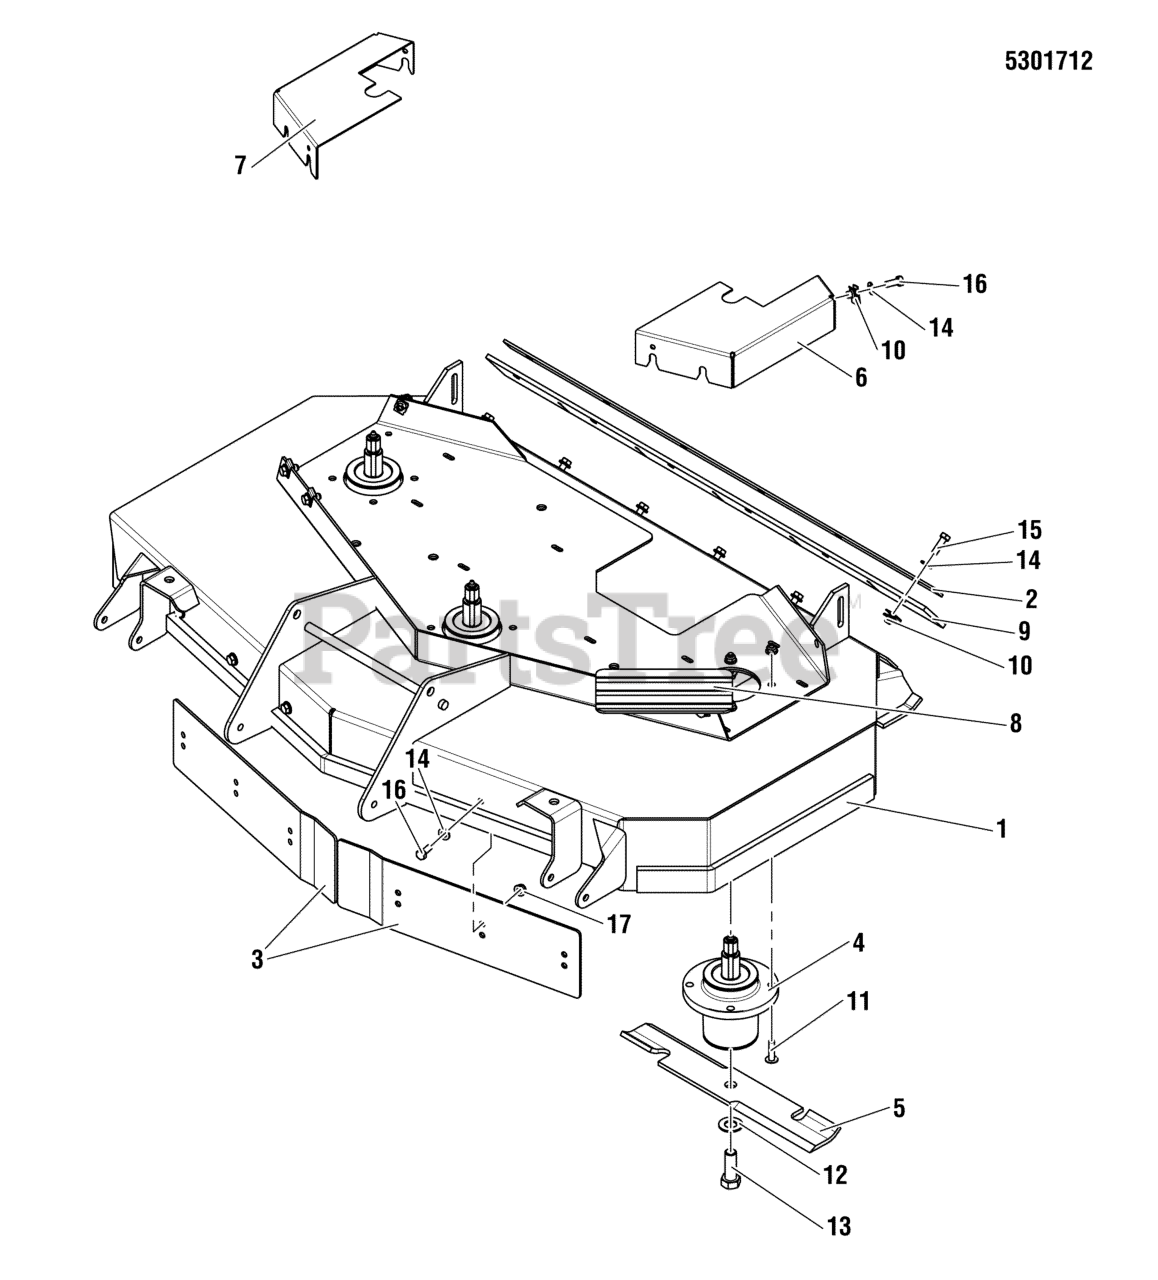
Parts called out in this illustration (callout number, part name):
1	DECK SHELL W/ DECALS, 44RD, IS1500ZCE
2	BAR, RETAINING, 44RD - BLK
3	BAFFLE, FRONT DISCHARGE, 44RD - BLK
4	ASSM, SPINDLE, LOW PROFILE
5	BLADE, 15" (SET OF THREE)
6	GUARD, 44" MOWER DECK, LH
7	GUARD, 44" MOWER DECK, RH
8	SAFETY WALK, 4.00 X 7.50
9	FLAP, RUBBER, 44RD
10	BODY CLIP, 5/16-18-7GA MATERIAL
11	BOLT, 5/16-18 X 1 1/4 FLANGE
12	WASHER, 5/8 GRADE 8, YZ
13	BOLT, 5/8-11 X 1-3/4 GD8
14	WASHER, 5/16" SAE
15	BOLT, 5/16-18 X 1 GD5 YZ
16	BOLT, 5/16-18 X 3/4 GD5
17	NUT, 5/16-18 HEX NYLOCK FLANGE
